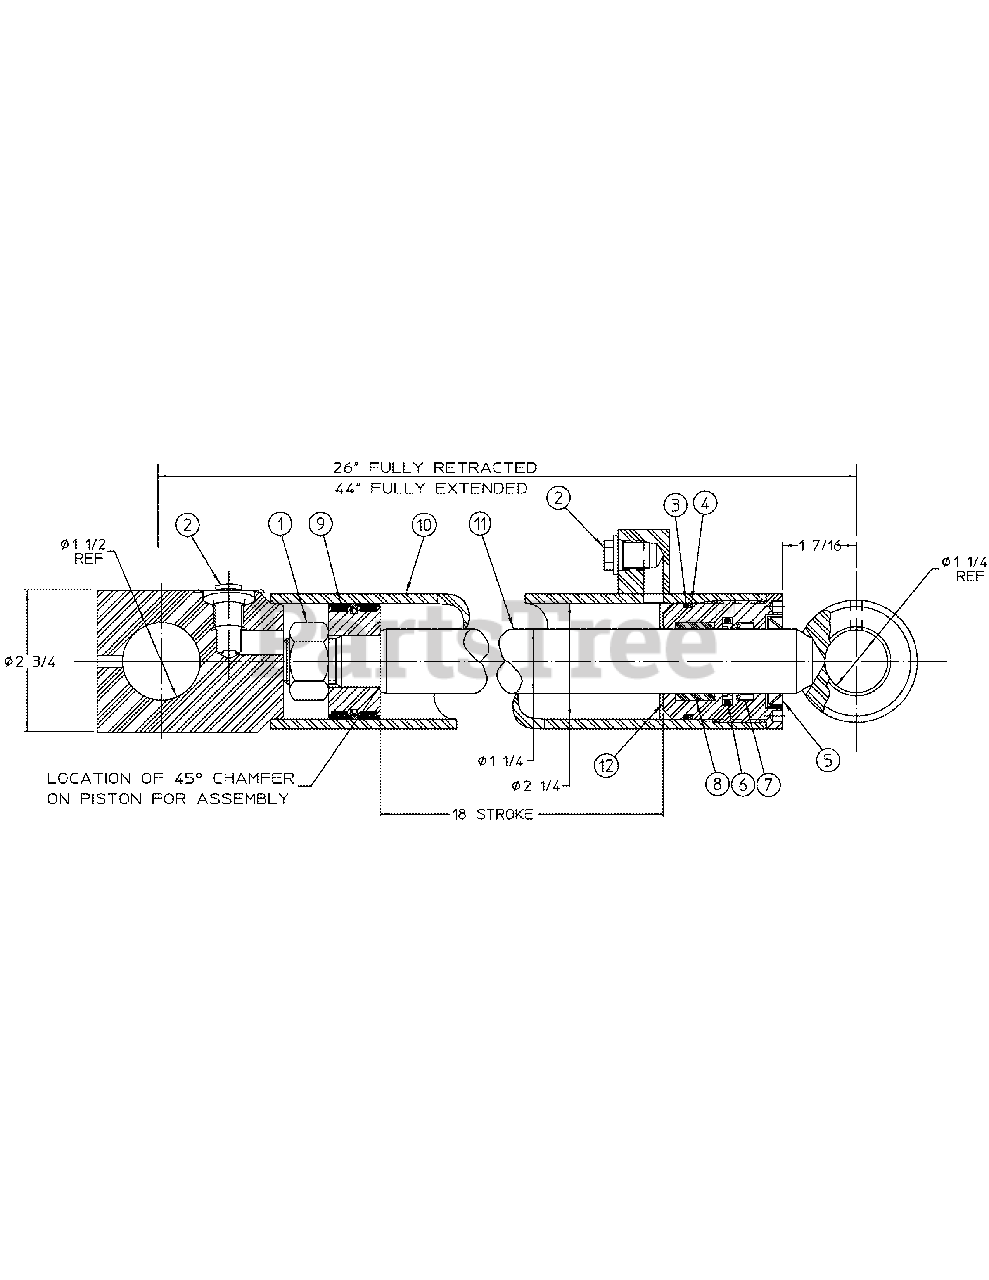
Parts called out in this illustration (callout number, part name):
1	Nut, 7/8" NF Lock
3	O-Ring, 2-1/4" OD x 2-1/16" ID
4	Back-Up Ring, 2.253" OD x 2.081 ID
5	Rod Wiper
6	Step Seal
7	Rod Seal
8	Wear Ring
9	Piston Assembly
10	Cylinder Tube Weldment
11	Piston Rod Weldment
12	Gland with O-Rings, Back-Up, etc.
